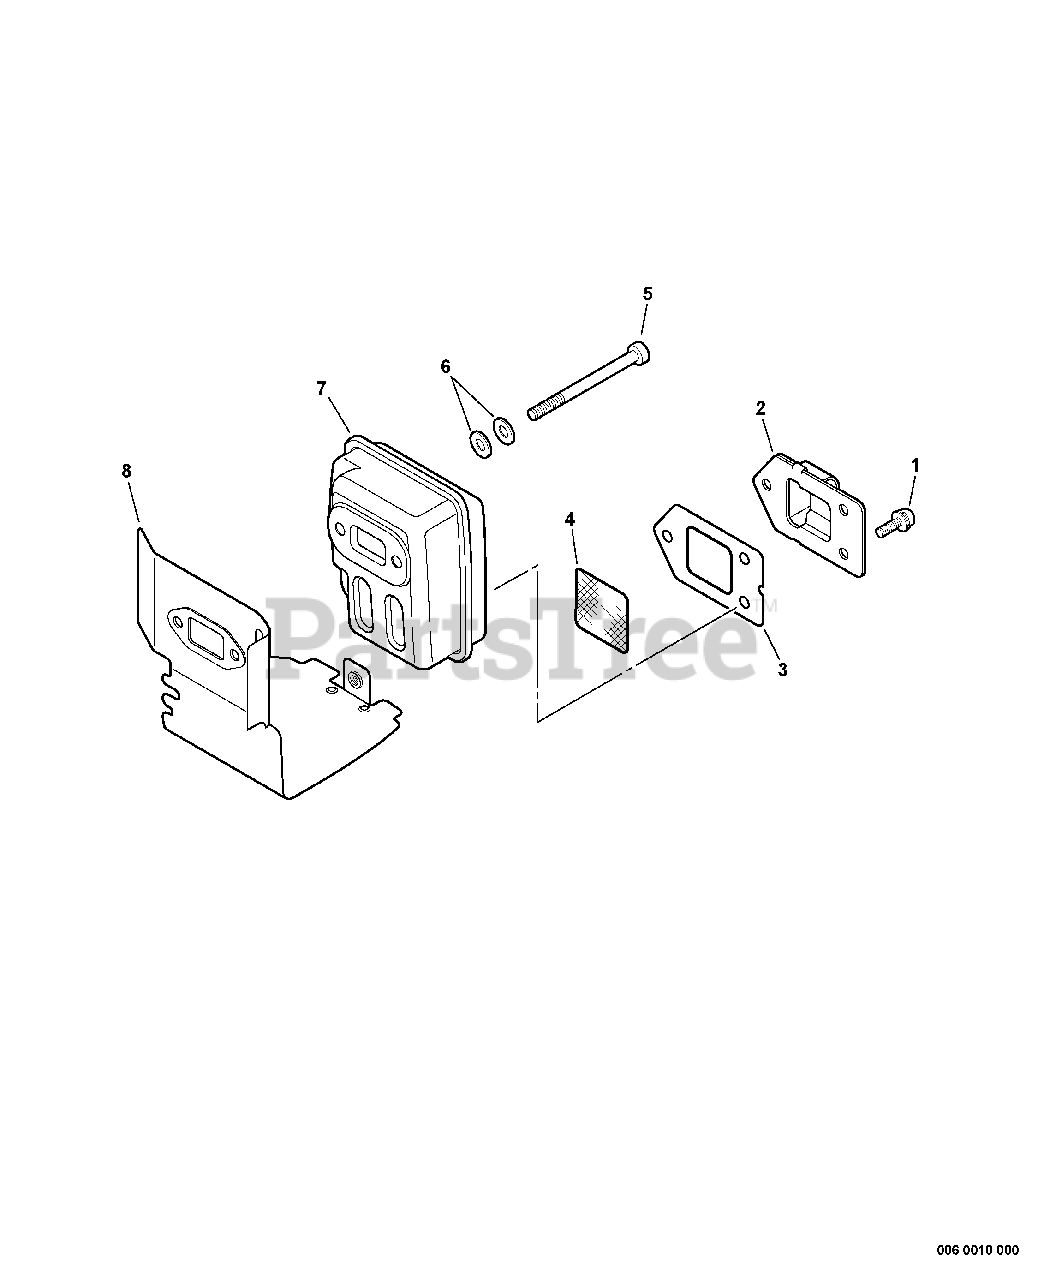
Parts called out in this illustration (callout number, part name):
1	SCREW 4×10
2	GUIDE, EXHAUST
3	GASKET, EXHAUST
4	SCREEN, SPARK ARRESTER
5	BOLT 5×55
6	WASHER, FLAT 5.5×10×0.8
8	HEAT SHIELD, EXHAUST
